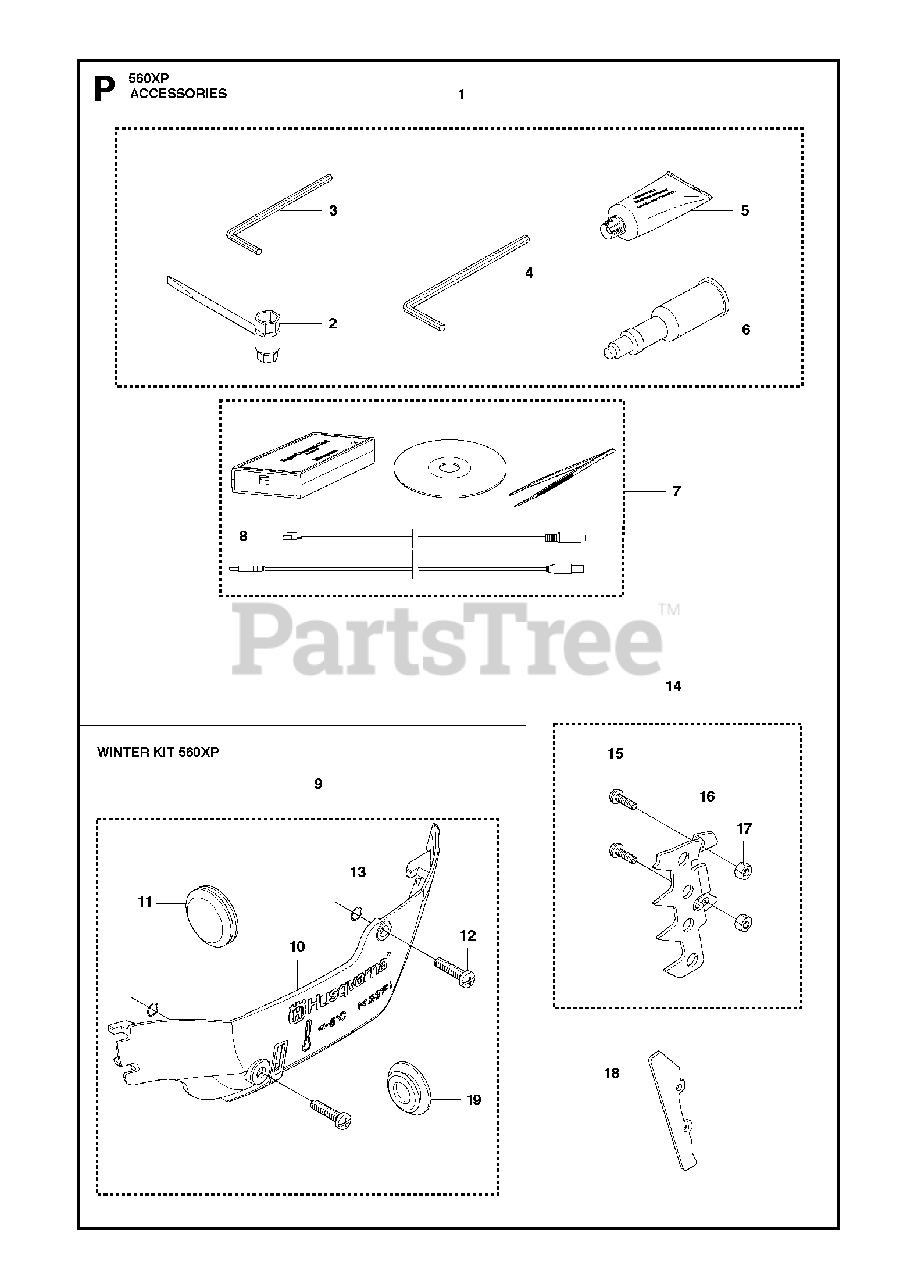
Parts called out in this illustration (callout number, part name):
2	COMBINATION WRENCH
3	L-SPANNER
4	L-SPANNER
5	GREASE
6	Grease Gun
7	SERVICE TOOLS
8	CABLE ASSY
9	WINTER KIT
10	WINTER COVER
11	PLUG
12	SCREW
13	O-RING
14	SPIKE OUTER
15	SCREW
16	SPIKE OUTER
17	NUT
18	RP ENCLOSED KIT
19	WINTER PLUG
